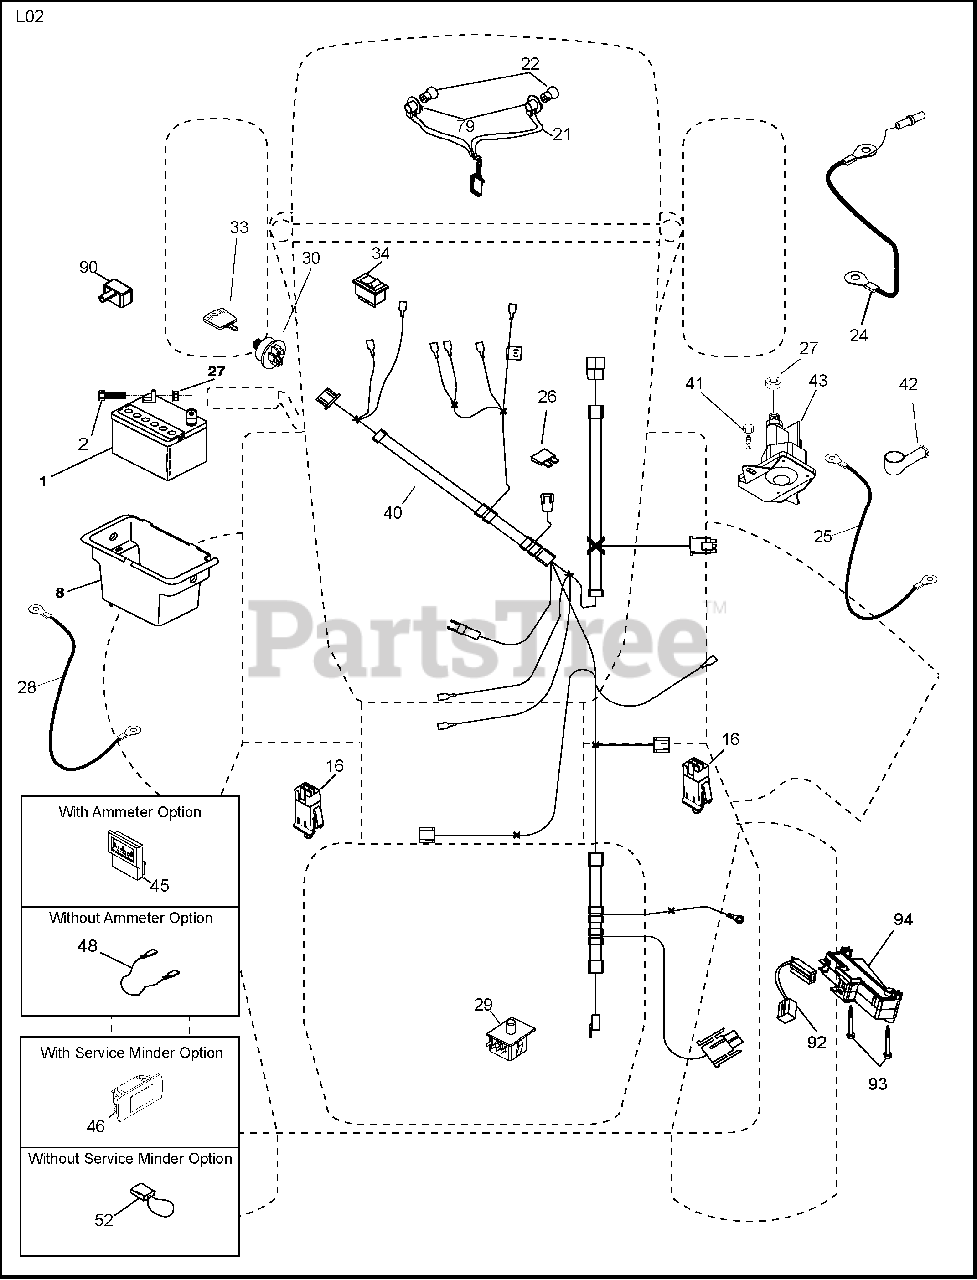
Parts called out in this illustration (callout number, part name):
1	Battery
2	Bolt Hex Hd. 1/4-20 unc x 3/4
8	Box Battery
16	Switch Interlock
21	Harness Asm. Light w/4152j
22	Bulb Light #1156
24	Cable Battery 6 Ga. 11" Red
25	Cable Battery
26	Fuse 20 AMP
27	Nut Keps Hex 1/4-20 unc
28	Cable Ground 6 Ga. 12" Black
29	Switch Seat
30	Switch Ign.
33	Key/Chain
34	Switch Light/Reset
40	Harness Ign.
41	Bolt Blk. Fin Hex 1/4-20
42	Cover Terminal Red
43	Solenoid
48	Adapter Ammeter
52	Protection Wire Loop
79	Socket Asm. Bulb Twistlock
90	Cover Terminal Battery
92	Harness Pigtail
93	Screw Plastite 10-14 x 2.0
94	Module Reverse ROS
